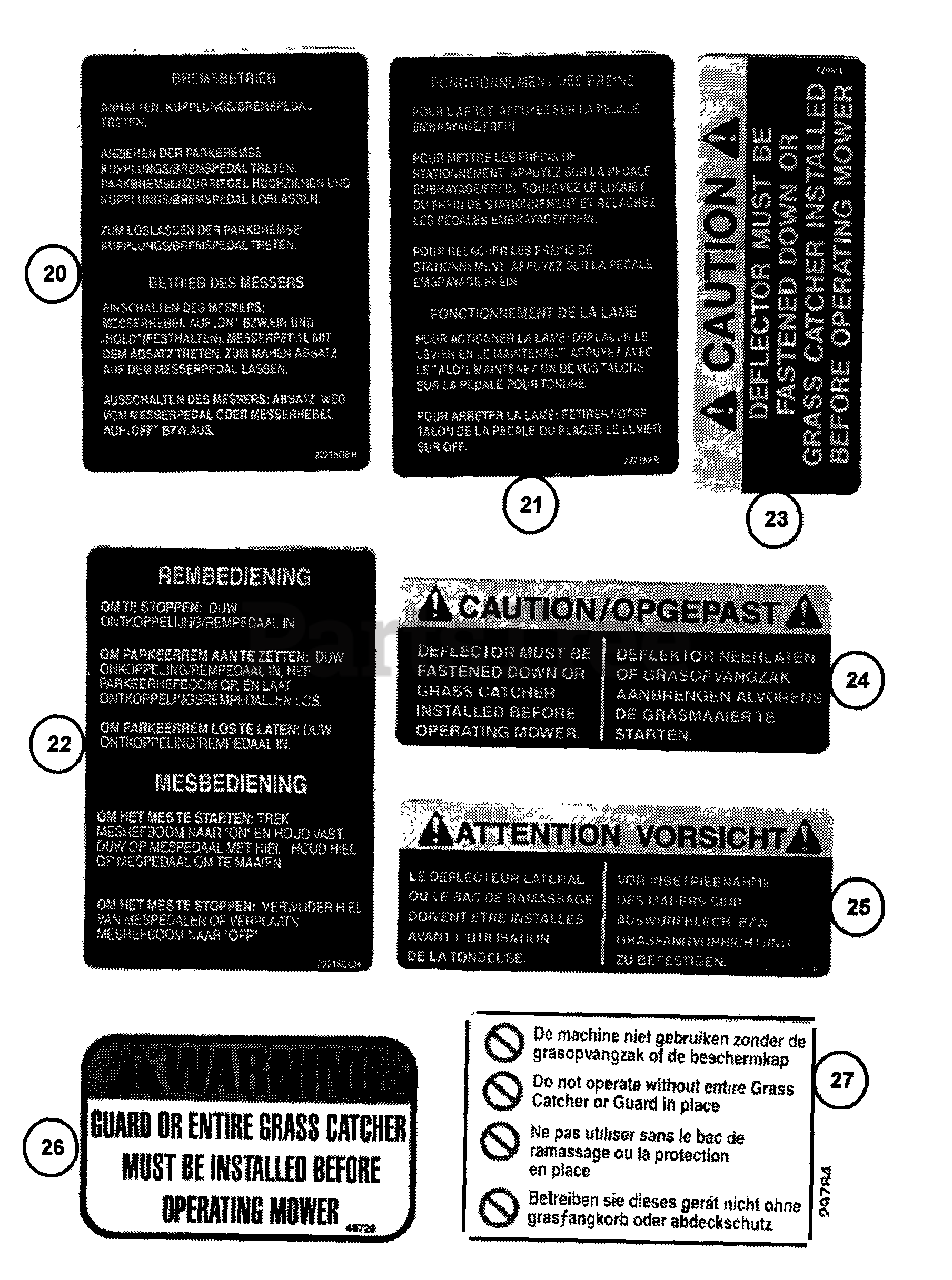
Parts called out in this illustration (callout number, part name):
20	DECAL,
21	DECAL,
22	DECAL,
23	DECAL,
24	DECAL,
25	DECAL,
26	DECAL,
27	DECAL,
